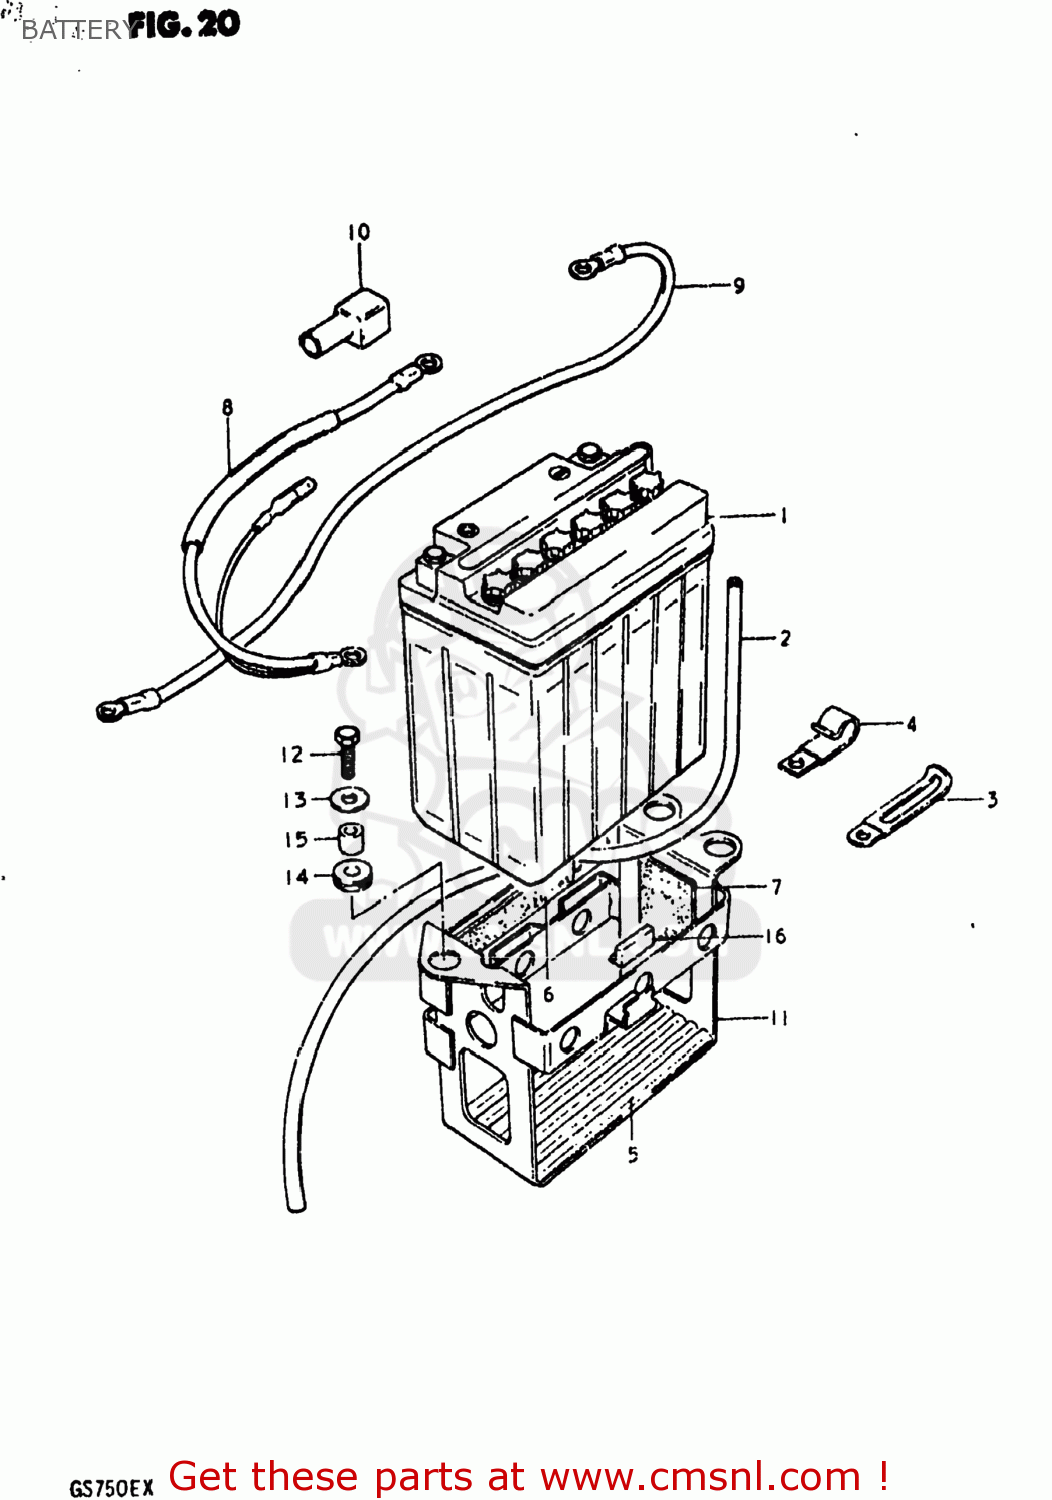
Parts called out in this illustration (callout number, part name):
1	BATTERY ASSY (12V)
2	HOSE,BATTERY EXHAUST
3	CLAMP L:35
4	CLAMP
5	PROTECTOR,BATTERY
6	PROTECTOR(20X90)X4
7	PROTECTOR,BATTERY
8	WIRE,BATTERY PLUS
9	LEAD WIRE,BATTERY(-)
10	CAP,TERMINAL
11	HOLDER,BATTERY
12	BOLT, UPPER
13	WASHER
14	CUSHION
15	SPACER(6.1X9X7.5)
16	CUSHION,FRAME COVER
